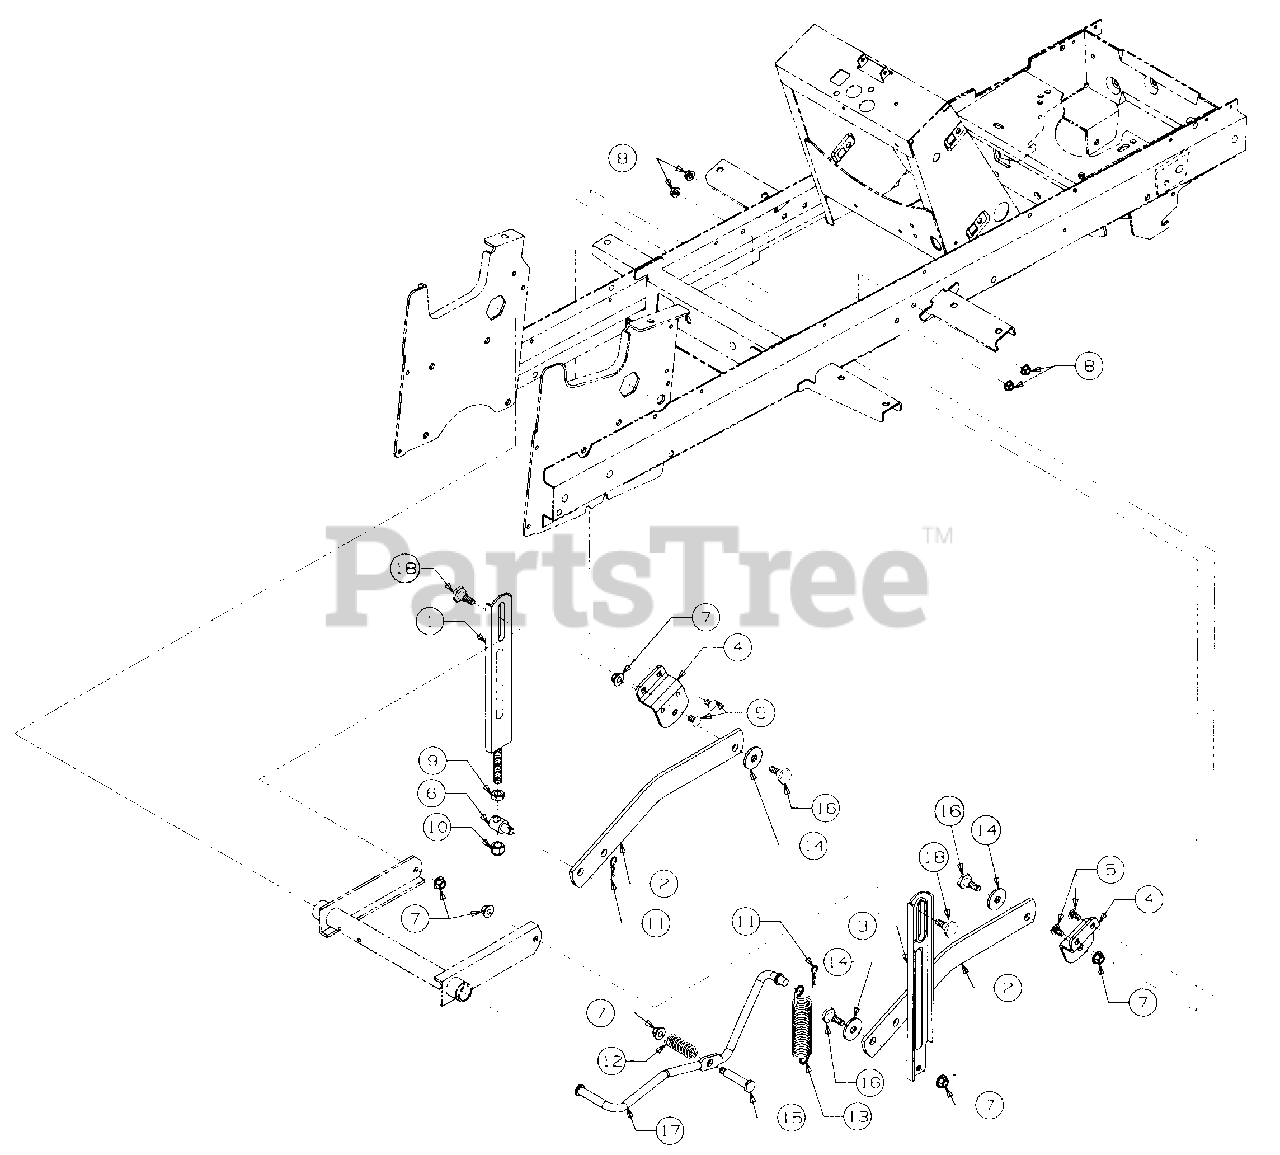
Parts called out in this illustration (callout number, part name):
2	Link, Lift
5	Bolt, Carriage, 5/16-18 x .62 Lg...
6	Ferrule, Adjustment
7	Nut, Hex Flanged Lock, 3/8-16
8	Nut, Hex Flange Top Lock 5/16-188
9	Nut, Hex Jam, 1/2-13 GR5
10	Nut, Hex Top Nylon Lock, 1/2-13
11	Pin, Internal Cotter, .092 Dia x 1.63 Lg
12	Spring, Compression, .63 ID x 2.0 Lg
13	Spring, Extension, 1.0 OD x 6.42 Lg, 43 Coils, Light Duty 46" Deck
14	Washer, Flat, .50 x 1.5 x .15 Thk
15	Bolt, Shoulder
16	Bolt, Shoulder
17	Rod, RH Lift Assist
18	Bolt, Shoulder
